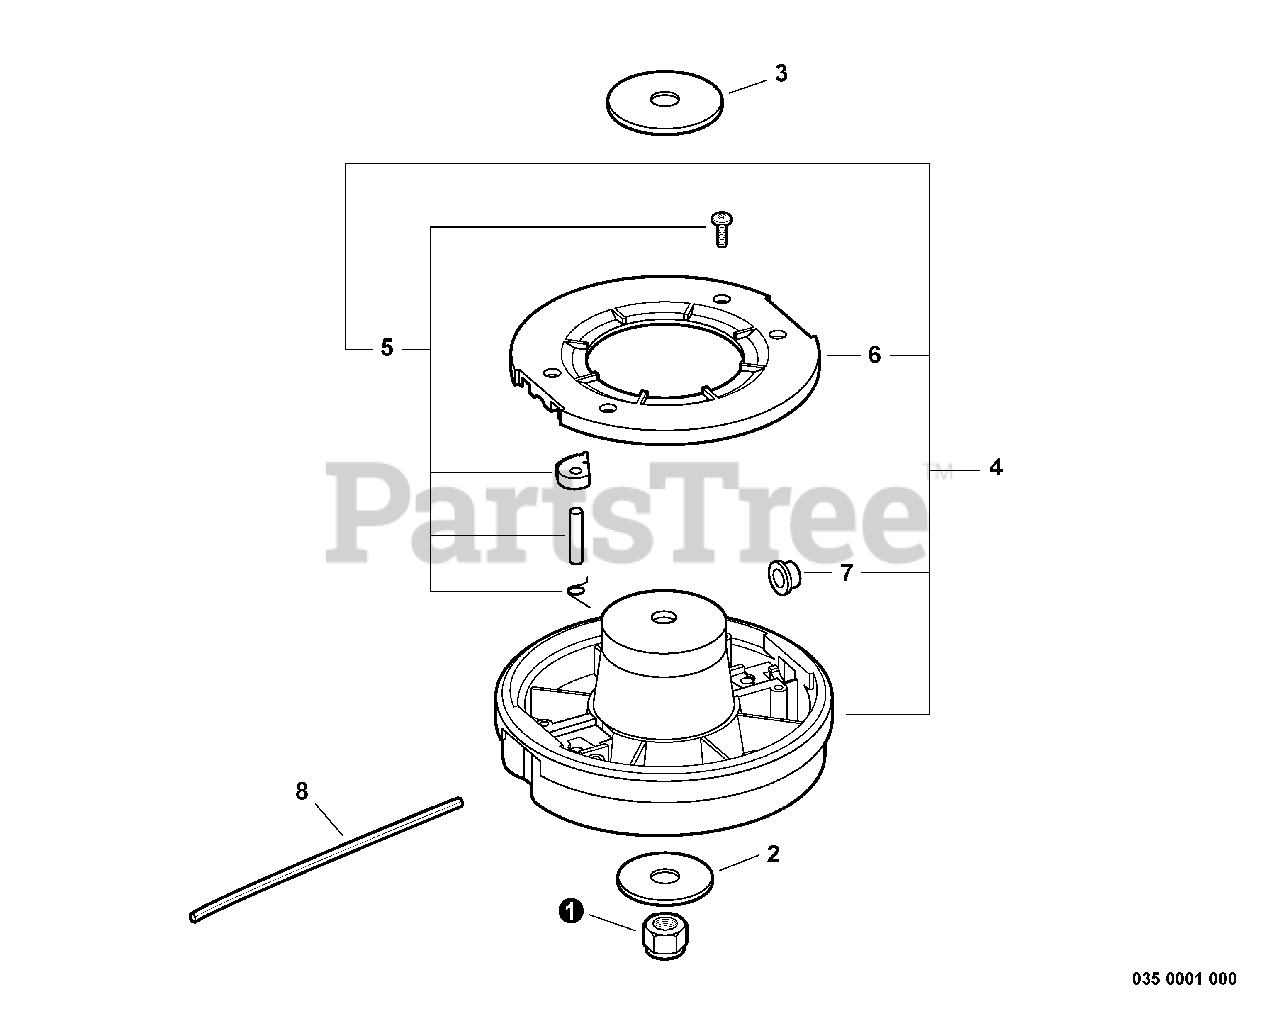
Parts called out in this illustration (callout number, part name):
1	LOCKNUT
2	WASHER - 8
3	WASHER - 10
4	TWO LINE RAPID LOADER ATTACHMENT
5	REPAIR KIT
6	COVER - TOP
8	LINE, TRIMMER - 0.080 DIA
